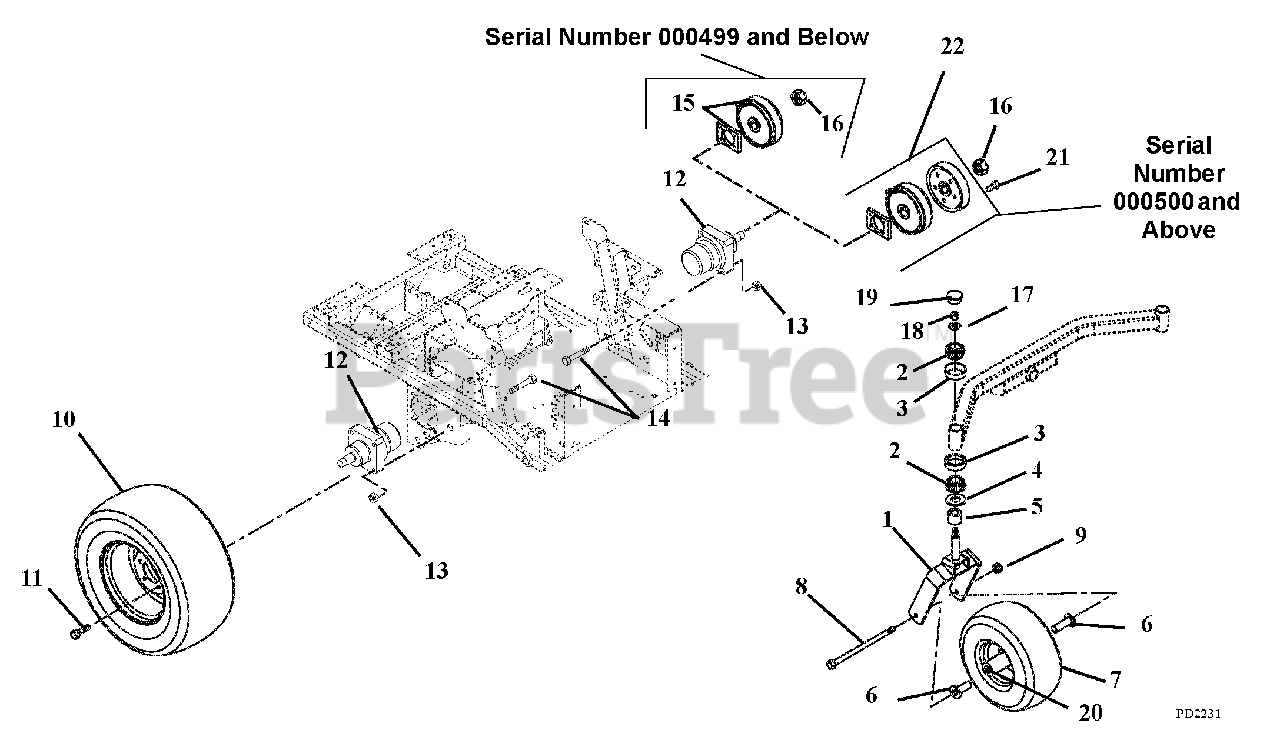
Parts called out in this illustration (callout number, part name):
1	Fork, Front
2	Bearing, Cone w/ Grease
3	Bearing, Cup 1.980 x .420
4	Bearing Seal 1.5 x 2 x .18
5	Spacer, PM, 1.03 I.D. x 1.5 O.D. x .375
6	Spacer, Wheel
7	Wheel/Tire Assembly
8	Bolt, Hex .50-13 x 9.00 Grade 5
9	Nut, Locking Center .50-13
10	Tire/Wheel Assembly 24 x 12-12
11	Bolt, Lug .50-20 x 1.38 Grade 8, 60 Degree
12	Hydraulic Wheel Motor (Includes item 16) (992136, 137, 138)
13	Nut, Locking Top Flange .50-13
14	Bolt, Wheel Motor .50-13 x 2.75
15	Kit, Parking Brake Service (Serial Number 000499 and below)
16	Nut , Lock Jam Patch (Included with 12)
17	Washer, Flat Steel 812 x 1.50 x .135
18	Nut, Jam Center-Lock .75-16
19	Cap, Dust
20	Bearing, 25mm I.D. x 52mm OD x 15mm
21	Bolt, Hex .31-18 x 1.5 Grade 5 (Serial Number 000500 and above)
22	Kit, Parking Brake Service (Serial Number 000500 and above)
